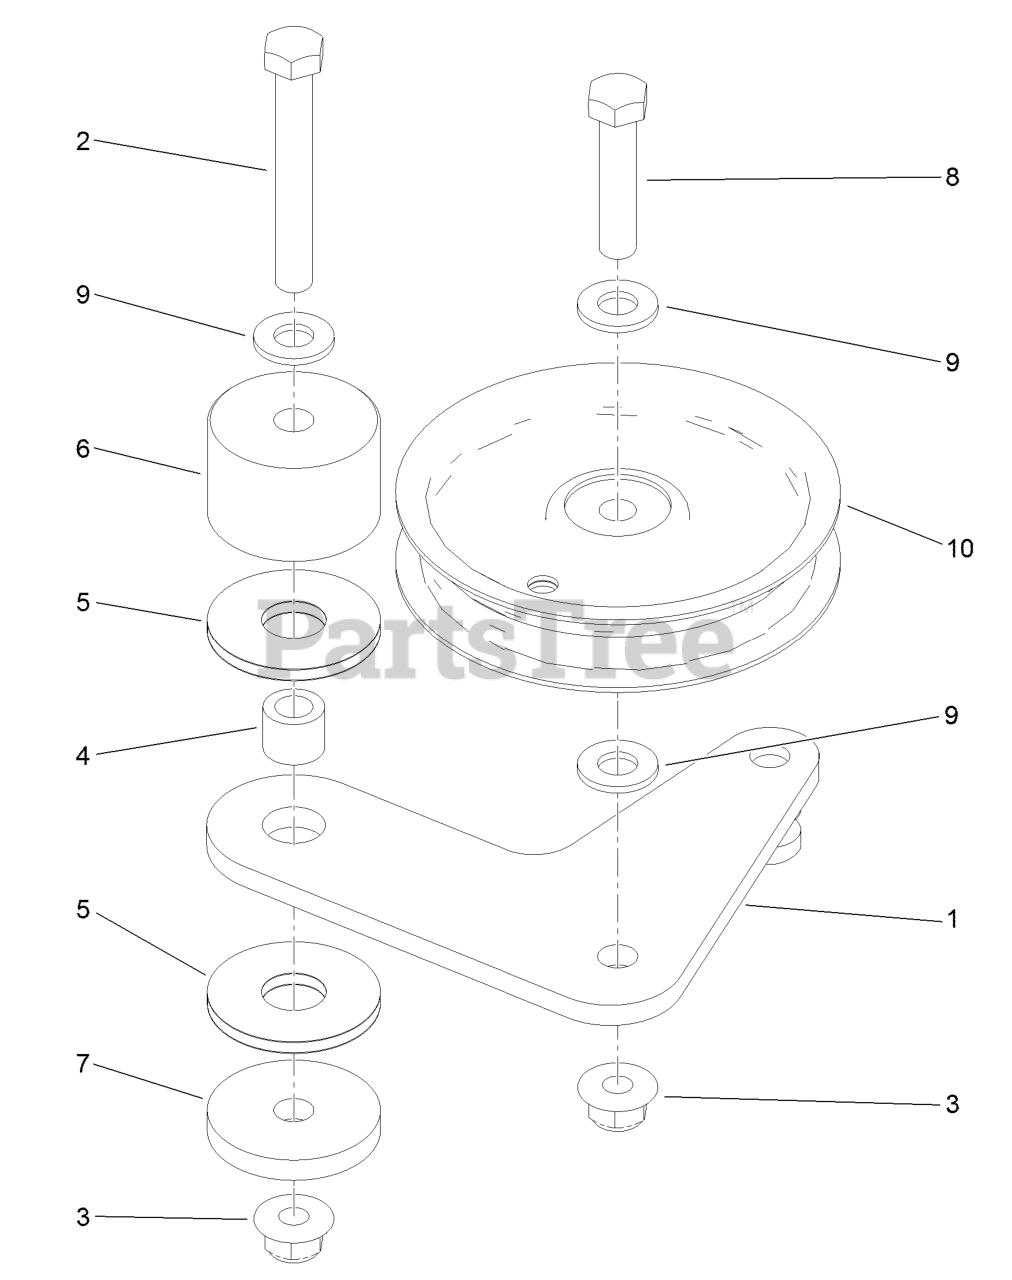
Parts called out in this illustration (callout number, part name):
1	PLATE-IDLER
2	SCREW-HH
3	NUT-HF, NI
4	BUSHING-LEVER, LIFT
5	WASHER-FRICTION, COMPOSIT
6	HUB-IDLER
7	WASHER-PLAIN
8	SCREW-HH
9	WASHER-FLAT
10	PULLEY-IDLER
